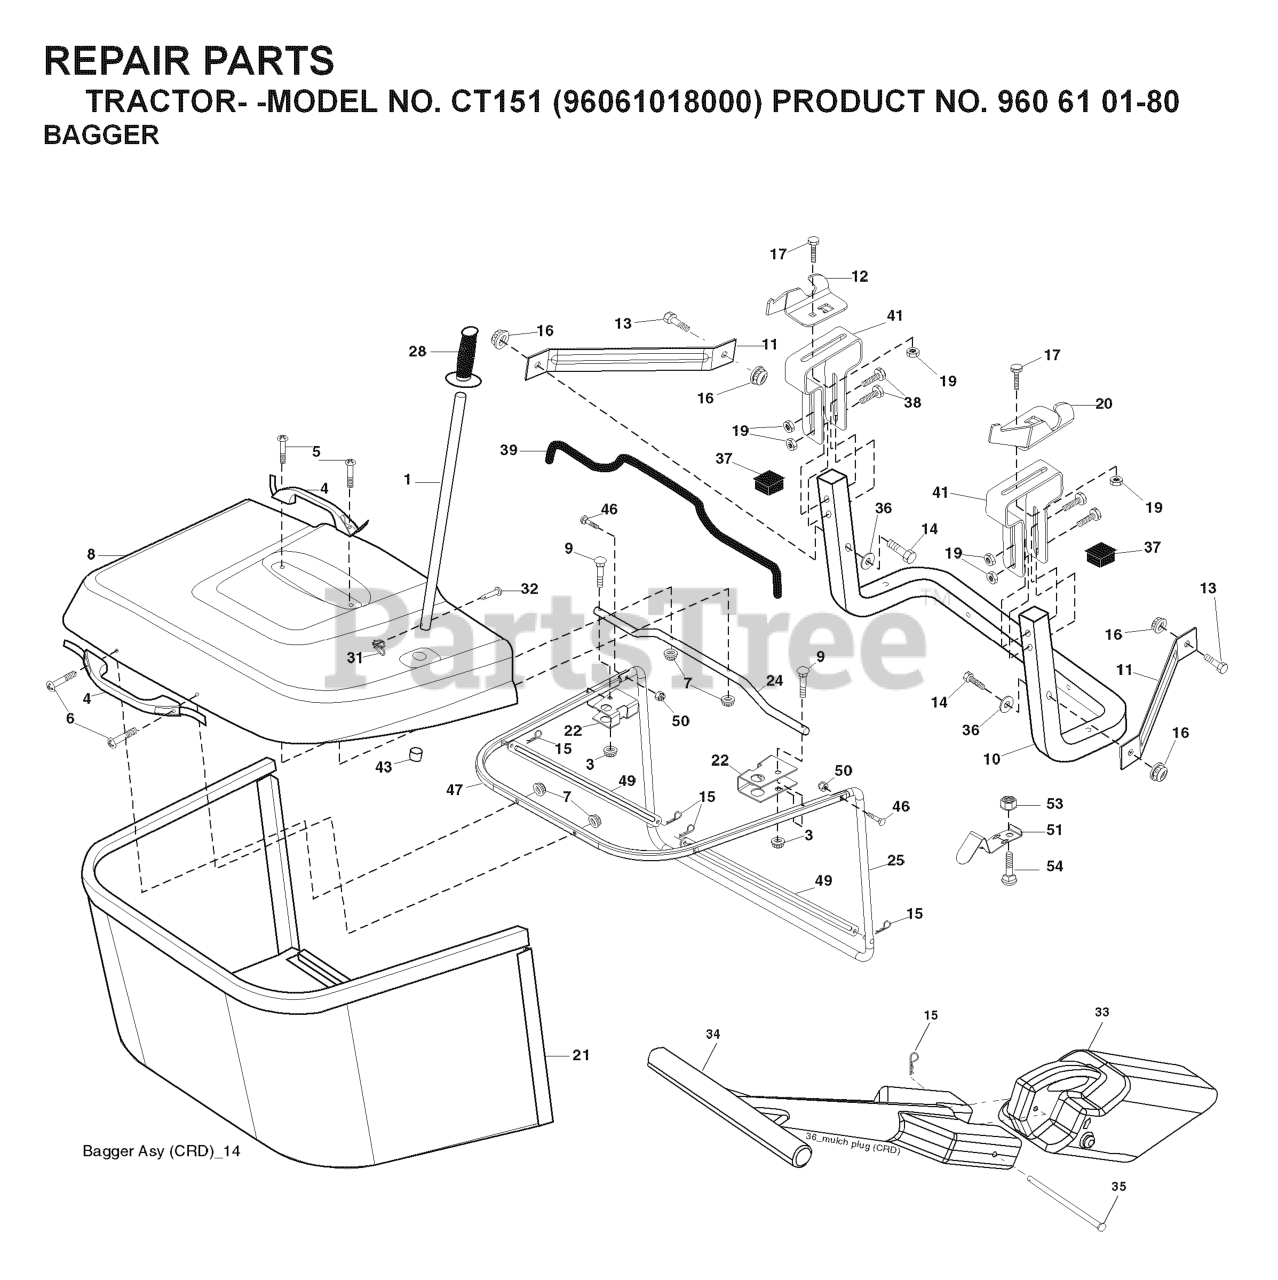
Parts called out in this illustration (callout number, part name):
1	KNOB, THREADED
4	HOSE CLAMP
5	CABLE HOLDER
9	CONNECTOR, BALL JOINT
10	LOCKNUT M6
13	SCREW EHHFM
18	SHOCK ABSORBER
22	THROTTLE CONTROL ASSY SINGLE
24	BRAKE LEVER ASSY
